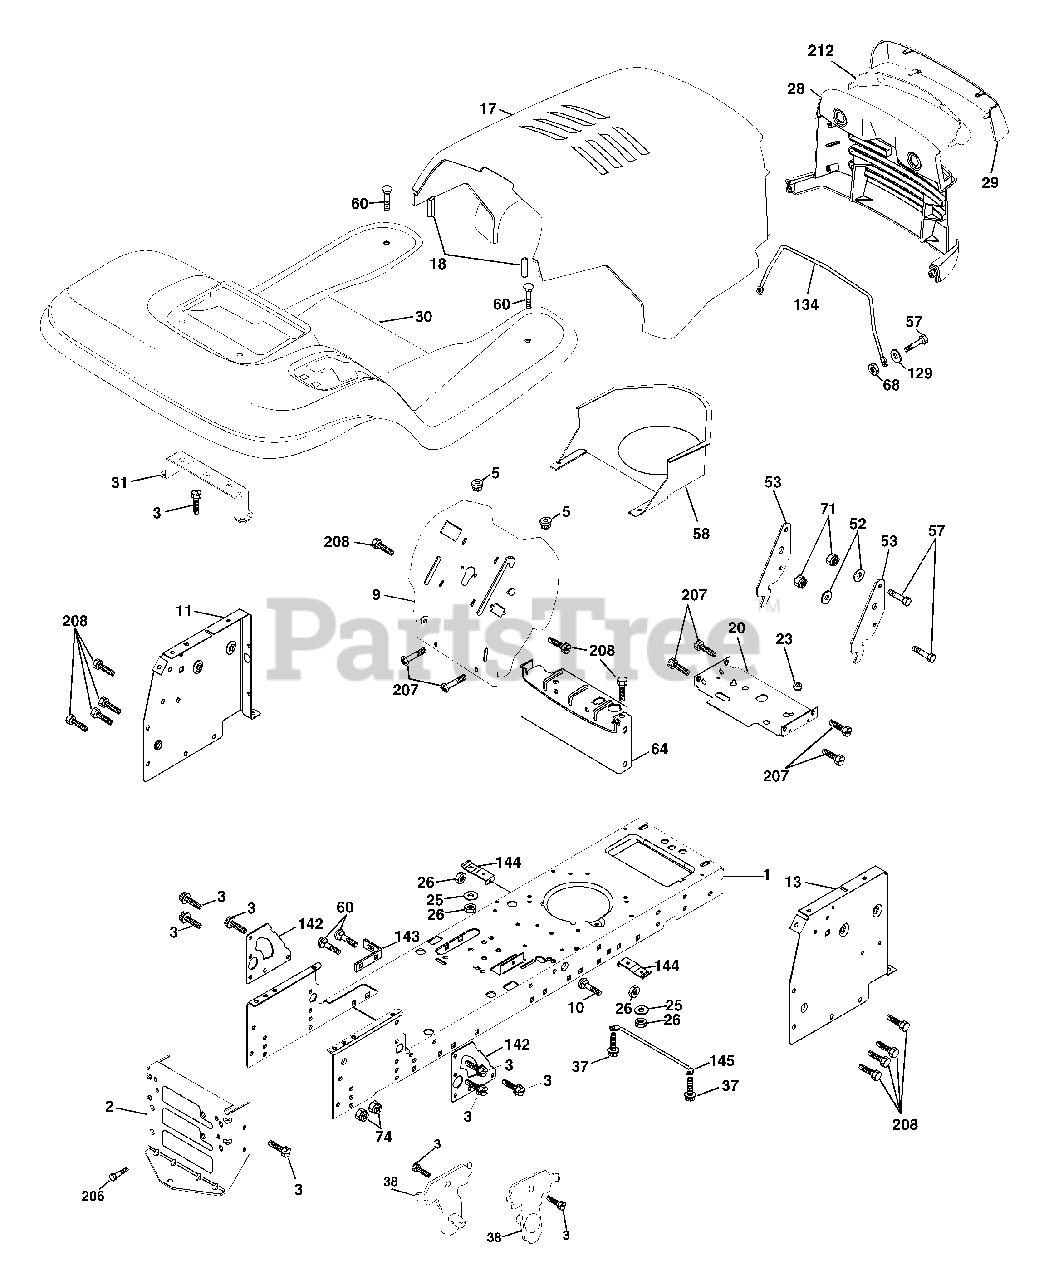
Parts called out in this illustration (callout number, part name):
1	Chassis Stamping
2	Drawbar
3	Screw 3/8-16x3/4
5	Bumper Hood/Dash
9	Dash P/L M
10	Bolt Carriage 3/8-16 x 1
11	Panel Dash Lh
13	Panel Dash Rh
17	Hood LT/PL Husqvarna
18	Bumper Hood
20	Plate Mtg Battery Fuel Tank Fr
25	Washer 13/32 X 13/16 X 12 Ga
26	Nut Lock Hex W/Ins 3/8-16 Unc
28	Grille LT/PL Husqvarna
29	Lens LT/PL Husqvarna
30	Fender Footrest STLT Pnt
31	Bracket Support Fender
37	Screw Thdrol 5/16-18 x 1/2 TYT
38	Bracket Asm Pivot Mower Rear
52	Washer 9/32 x 7/8 x 16 Ga.
53	Bracket Pnt. Pick off LT/PL Husqvarna
57	Bolt Hex 1/4-20 x 3/4
58	Air Duct Engine P/L
60	Bolt Rdhd Sqnk 3/8-16unc x 3/4
64	Dash Lower STLT
68	Nut Keps Hex 1/4-20 Unc
71	Nut Crownlock 1/4-20 Unc
74	Nut Crownlock 3/8-16 UNC
129	Washer 9/32 x 5/8 x 16 Ga.
134	Rod Support Hood LT/PL Husq.
142	Plate Reinforcement STLT
143	Bracket Swaybar Chassis
144	Bracket Pnt Footrest STLT
145	Rod Pivot Chassis/Hood
206	Bolt Shoulder 5/16-18 TT
207	Screw Thdrol 5/16-18 x 1/2 TYTT
208	Screw Thdrol 3/8-16 x 1/2 TYT Bl
212	Insert Lens Reflect
